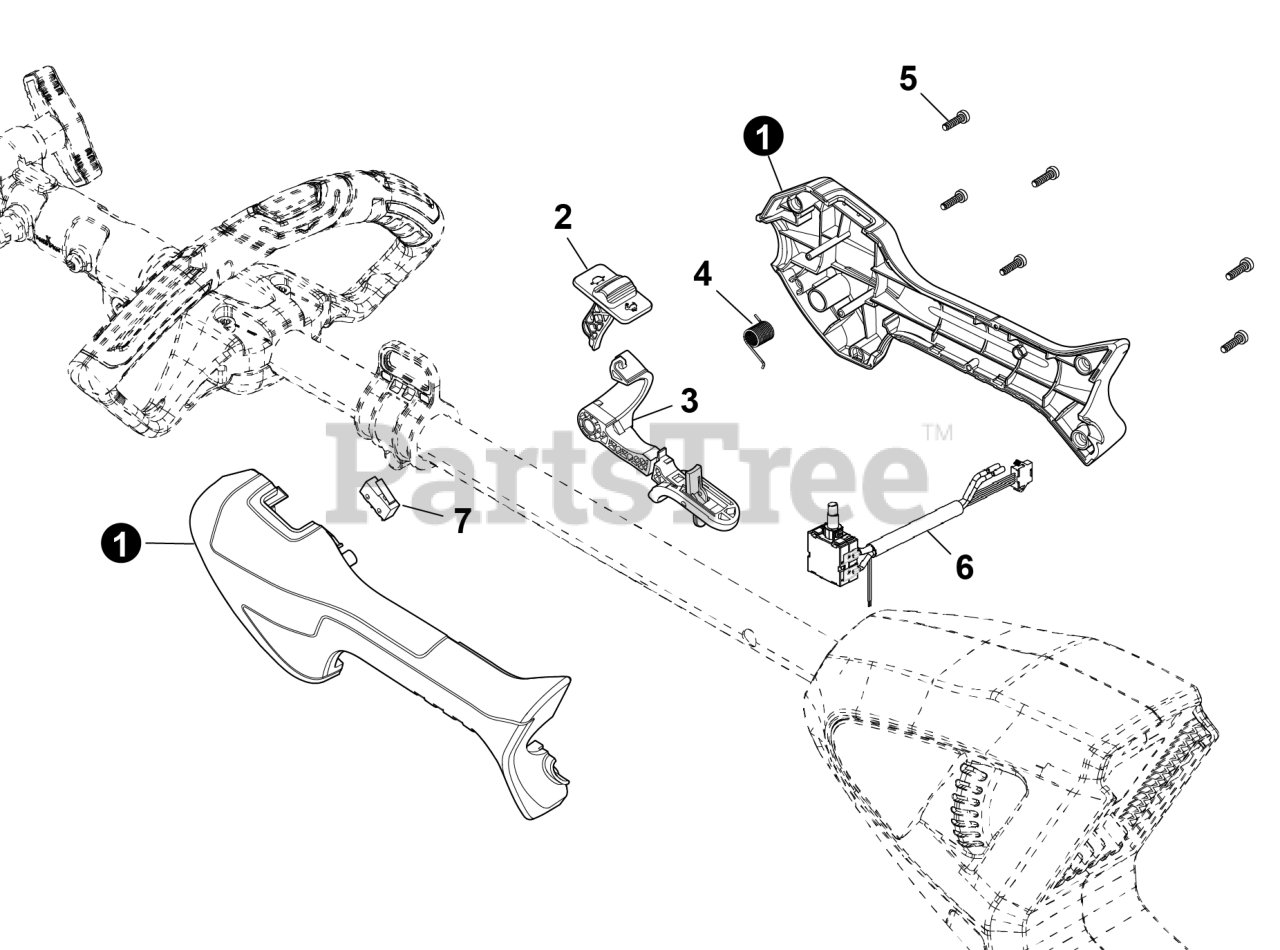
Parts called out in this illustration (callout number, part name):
1	HANDLE ASSY.
2	KNOB, SWITCH
3	LEVER ASSY.,THROTTLE
4	SPRING, TORSION
6	SWITCH, SPEED CONTROL
7	SWITCH, MICRO
